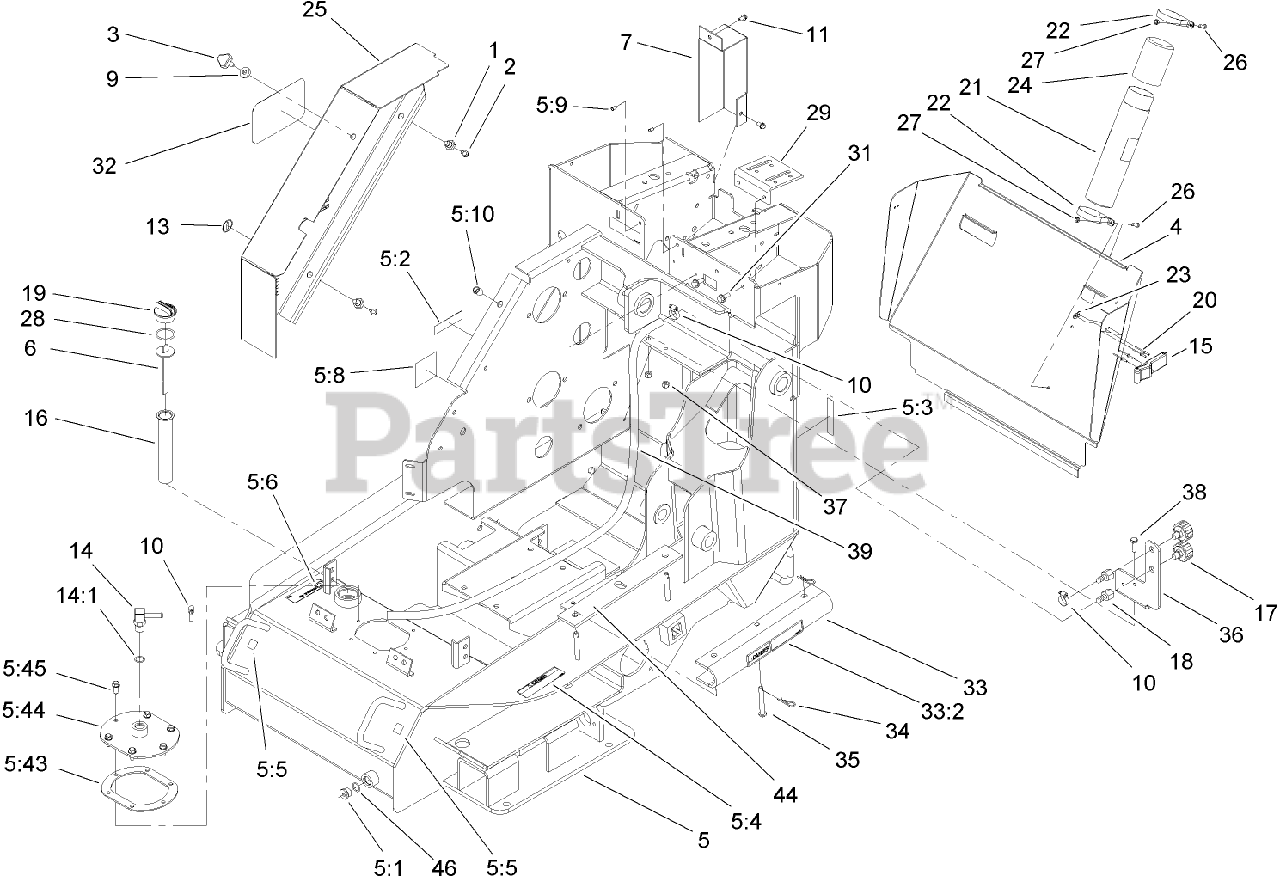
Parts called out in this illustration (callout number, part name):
1	MOUNT-SIDEPANEL
2	SCREW-PLASTITE
4	COVER-REAR
5	FRAME ASM
5:1	PLUG-HYD, HH
5:2	DECAL-COVER, MISSING
5:3	DECAL-BRAKE
5:4	DECAL-PINCH
5:5	DECAL-POINT, LIFT
5:6	DECAL-OIL, HYD
5:8	DECAL-BELT ROUTING
5:9	INSERT-NUT
5:10	INSERT-NUT
5:43	GASKET-COVER, ACCESS
5:44	COVER ASM
5:45	SCREW
6	DIPSTICK-OIL
7	COVER-PULLEY
9	WASHER-RUBBER
10	CLAMP-HOSE
11	SCREW-HWH
13	DECAL-GREASE
14	FITTING-HYD, 90 DEG
14:1	O-RING
15	LATCH
16	FILTER-SCREEN
17	BREATHER
18	FITTING-STRAIGHT
19	PLUG-PLASTIC
20	RIVET-POP
21	TUBE-MANUAL
22	CLAMP-R
23	WASHER-BACK
24	CAP-HOUSING
25	COVER-BELT
26	SCREW-PPH
27	NUT-LOCK, NI
28	O-RING
29	BRACKET-MOUNT, THROTTLE
31	SCREW-HWHTF
33	LOCKING ARM ASM
33:2	DECAL-DANGER
34	PIN-HAIR
35	PIN-CLEVIS
36	BRACKET-FILTER
37	NUT-LOCK, NI
38	SCREW-HH
39	HOSE-FUEL
44	PAD-RUBBER
46	O-RING
